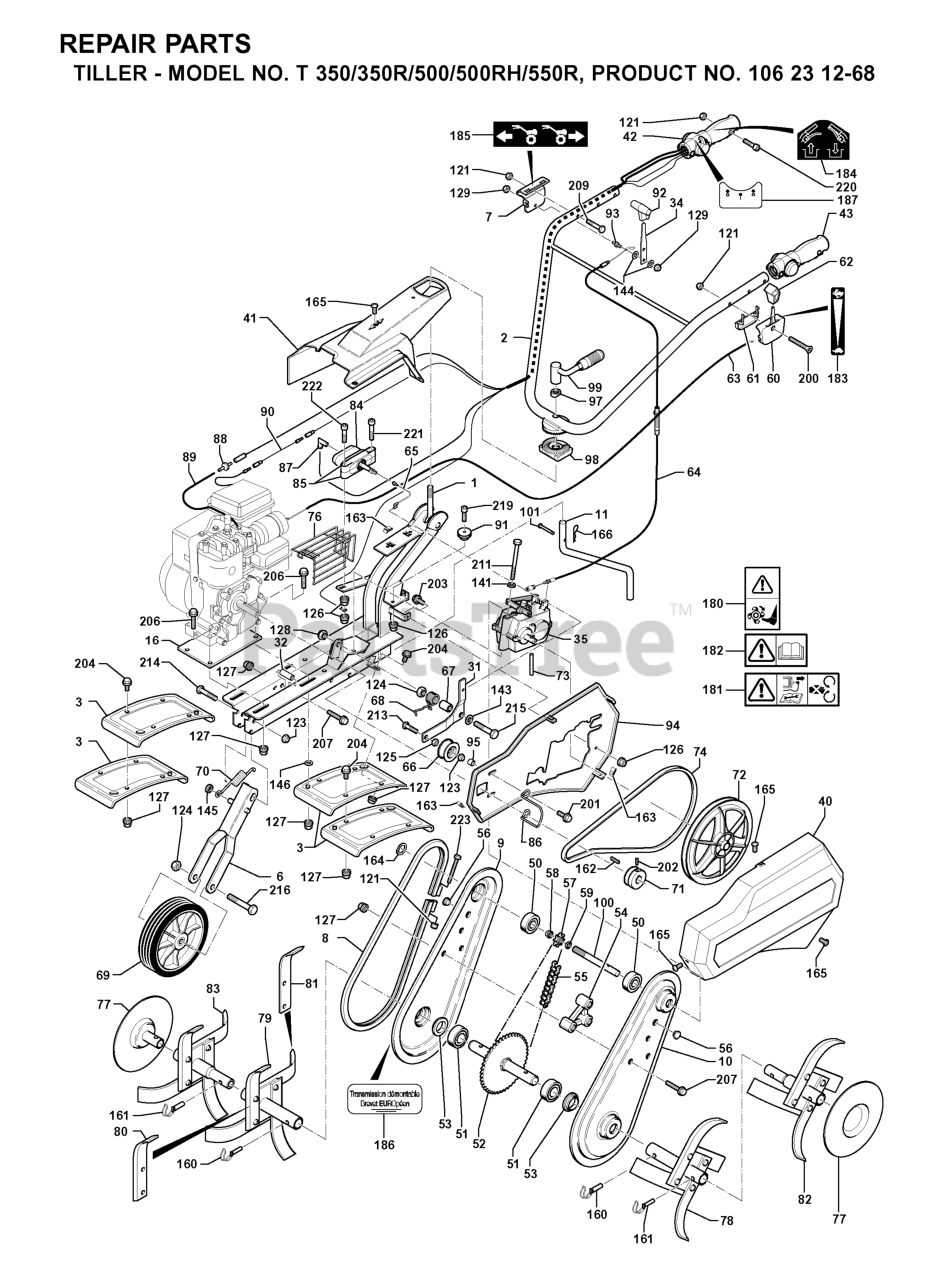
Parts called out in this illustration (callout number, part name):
31	ARM
53	SPACER SLEEVE
55	DRIVE CHAIN
60	THROTTLE TRIGGER
61	THROTTLE CONTROL
63	REPL BY 519 00 64-26
69	WHEEL
87	CONNECTION
121	Blocking nut M 6 Z
164	RETAINING RING
166	COTTER PIN
